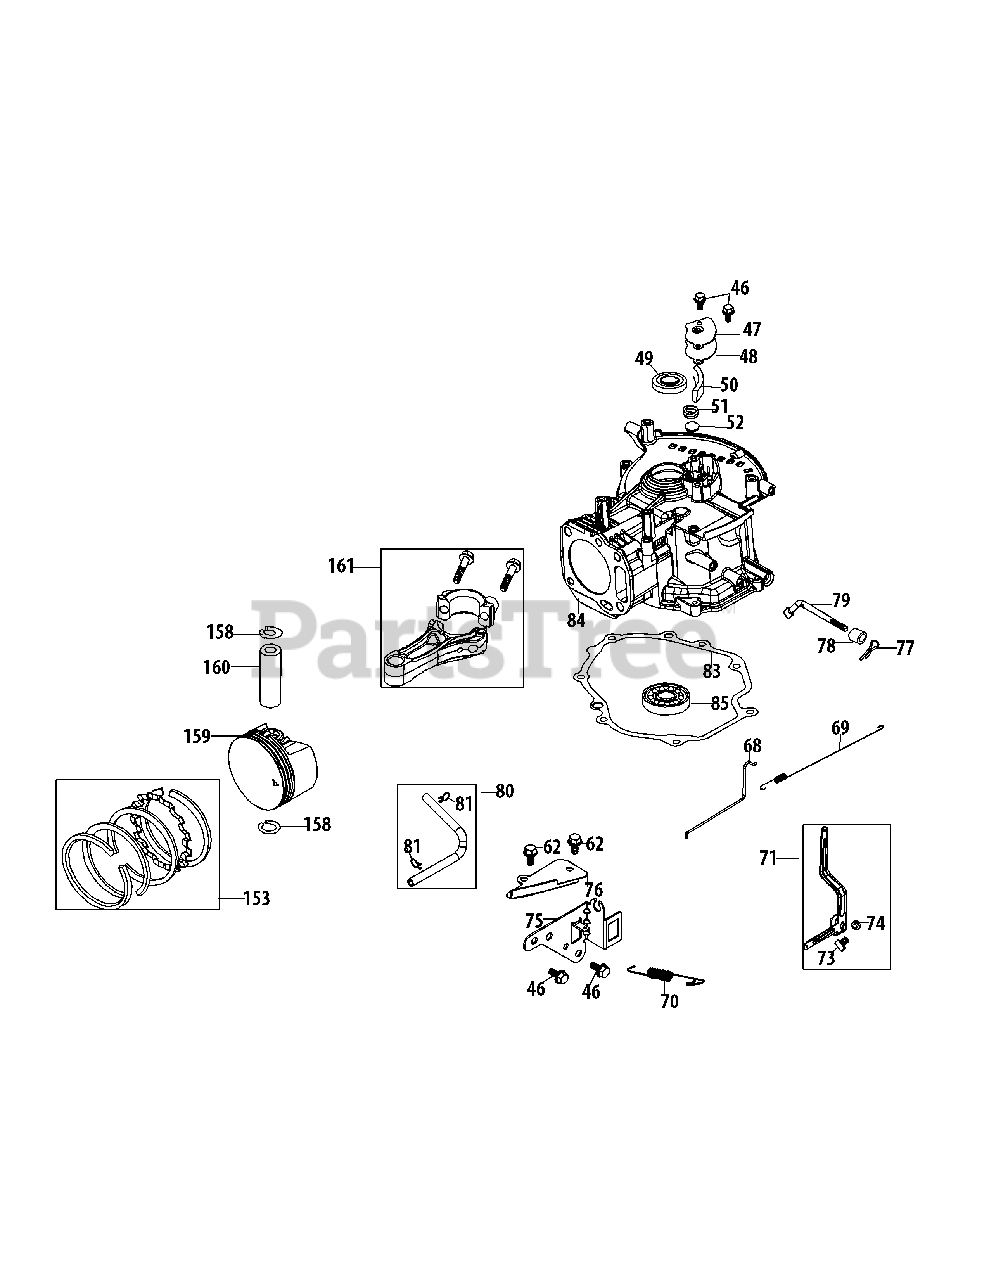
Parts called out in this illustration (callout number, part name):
46	Bolt M6X14 Multi-Purpose
47	Breather Cover Plate
48	Breather Gasket
49	Upper Crankshaft Seal
50	Breather Screen
51	Breather Valve Spring
52	Breather Valve
62	Bolt M6X12 Multi-Purpose
68	Throttle Linkage
69	Throttle Linkage Spring
70	Governor Spring
71	Governor Arm Assembly
73	Governor Arm Bolt
74	Governor Arm Nut M6
75	Component Bracket
76	Air Vane Cover Plate
77	Governor Arm Shaft Cotter Pin
78	Governor Seal
79	Governor Arm Shaft
80	Breather Hose Assembly
81	Breather Hose Clamp
83	Crankcase Cover Gasket
84	Crankcase
84	(Mtd Srvc Kit) Short Block
85	Main Bearing
153	Piston Ring Set
158	Piston Pin Snap Ring
159	Piston
160	Piston Pin
161	Connecting Rod Assembly
